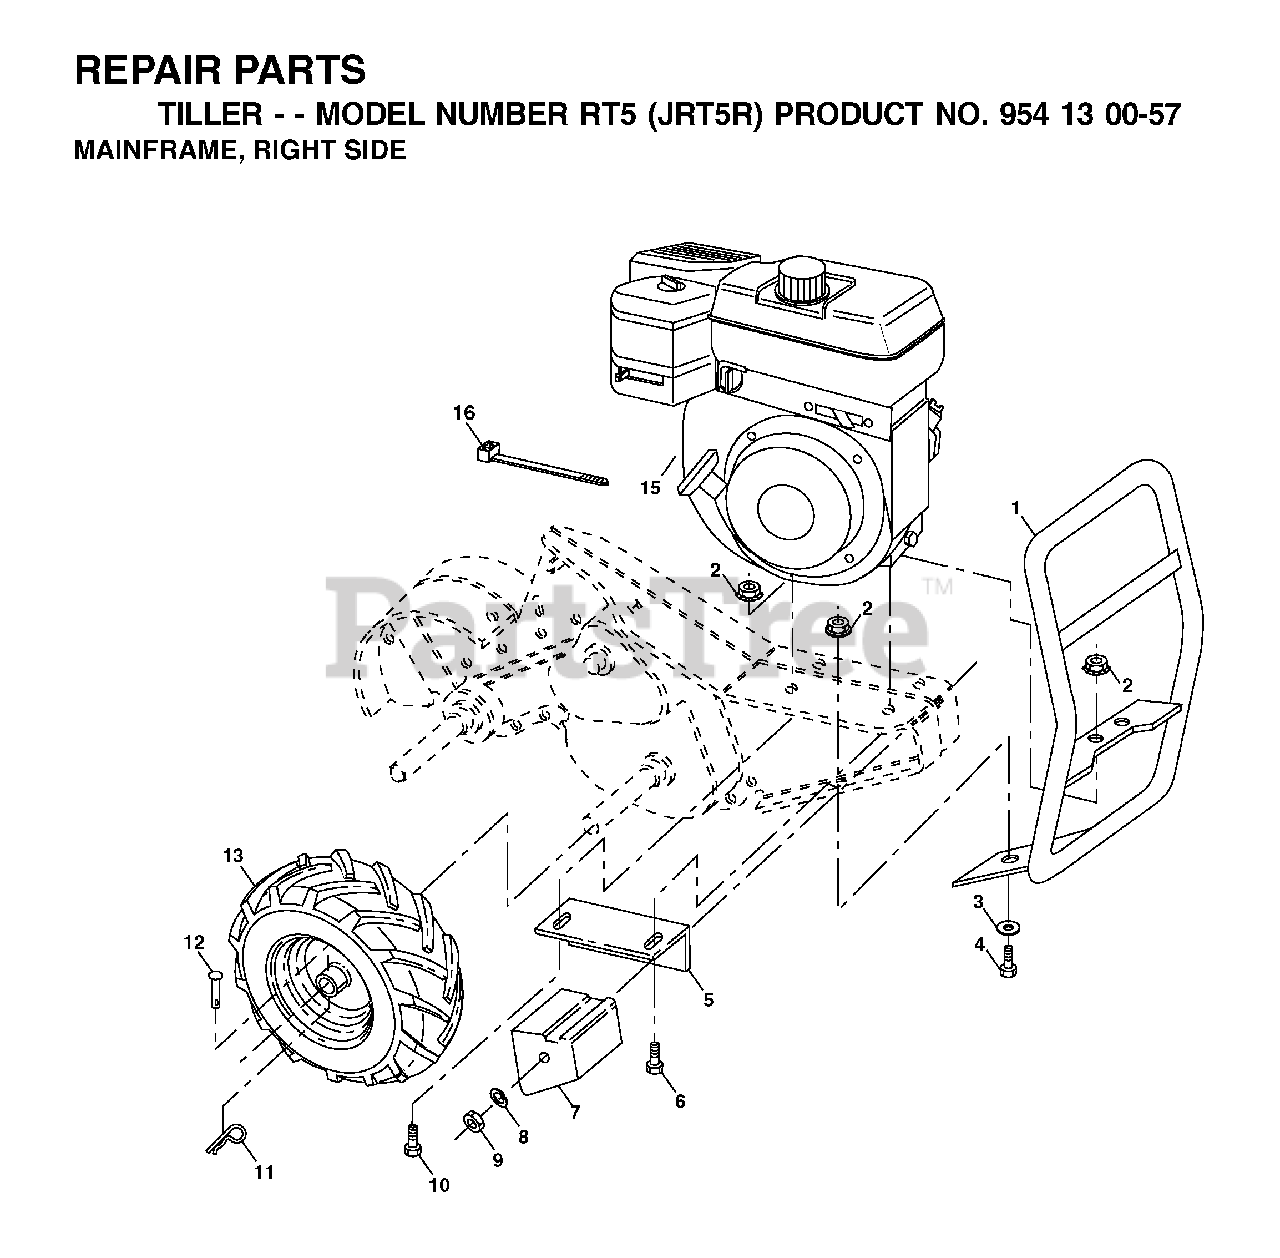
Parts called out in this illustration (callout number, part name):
1	BUMPER
2	LOCKNUT-FLANGE 5/16-18
3	WASHER
4	BOLT
5	BRACKET RH CRT
7	COUNTERWEIGHT, RH
8	WASHER, LOCK 3/8
9	NUT.HEX.3/8-16UNC
10	BOLT
11	RETAINER M
12	RIVET,DRILLED
16	TIE GUIDE
5321243-66	RIM
5321247-18	VALVE STEM LT
